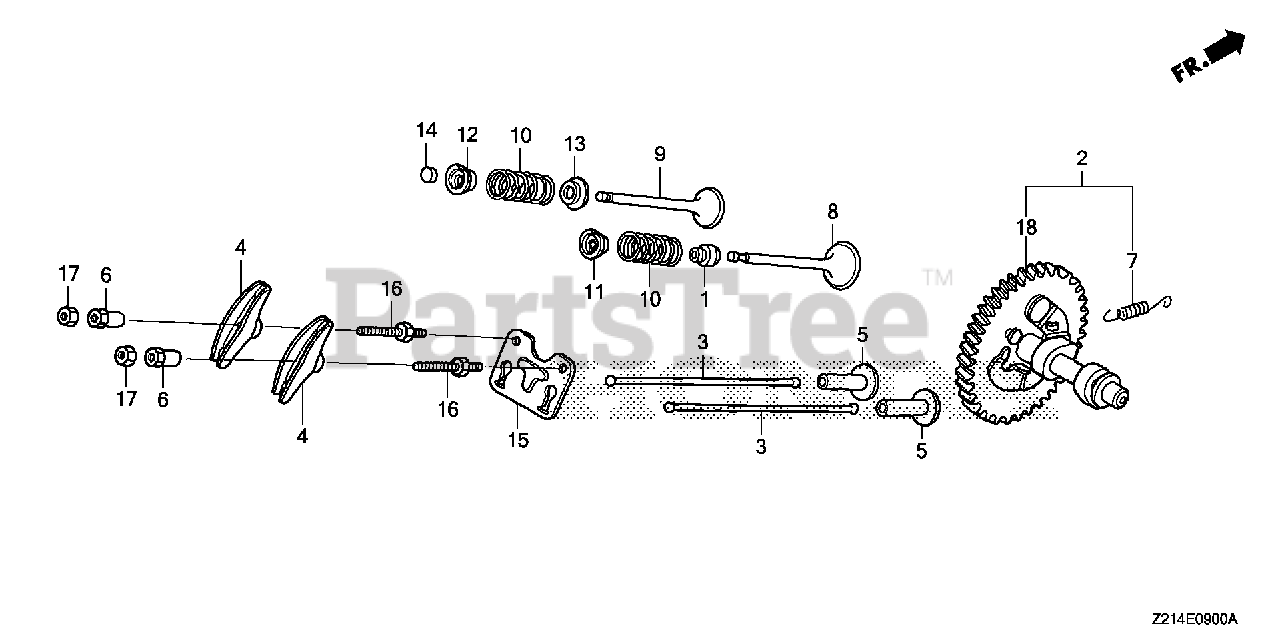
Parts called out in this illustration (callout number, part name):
1	SEAL, VALVE STEM
2	CAMSHAFT ASSY.
3	ROD, PUSH
4	ARM, VALVE ROCKER
5	LIFTER, VALVE
6	PIVOT, ROCKER ARM
7	SPRING, WEIGHT RETURN
8	VALVE, IN.
9	VALVE, EX. (STELLITE)
10	SPRING, VALVE
11	RETAINER, IN. VALVE SPRING (EXHAUST SIDE)
12	RETAINER, EX. VALVE SPRING
13	SEAT, VALVE SPRING
14	ROTATOR, VALVE
15	PLATE, PUSH ROD GUIDE
16	BOLT, PIVOT (8MM)
17	NUT, PIVOT ADJ.
